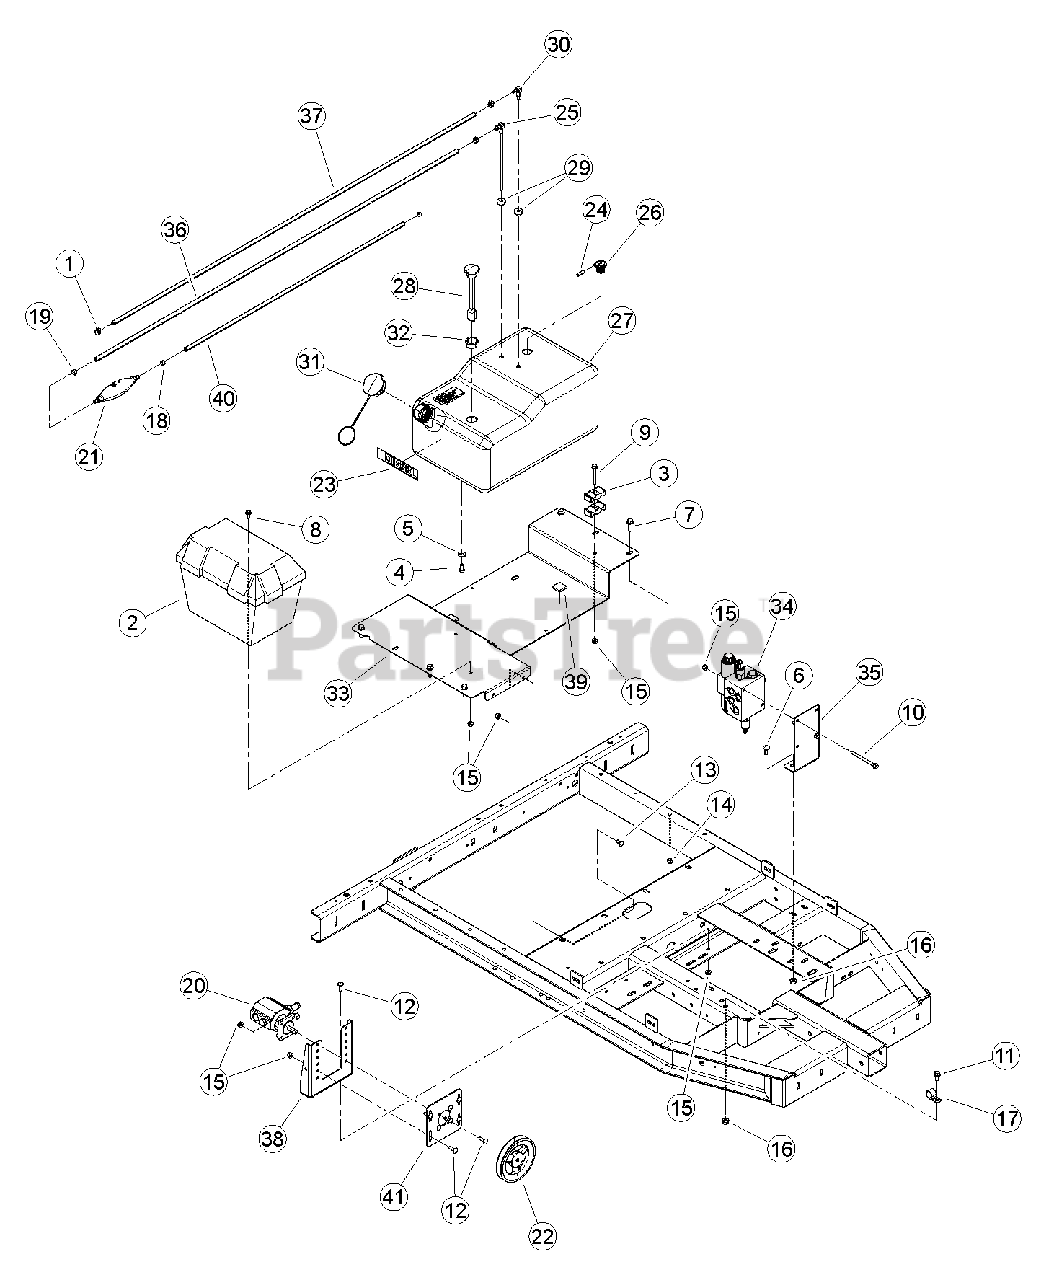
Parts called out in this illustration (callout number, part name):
1	CLAMP, HOSE 5/16 X 5/8 DIA MAX
2	BOX, PLASTIC BATTERY
3	CLAMP, PLASTIC HOSE
4	BOLT, 3/8 X 3/4 GR5 HEX CAPSCREW ZP
5	WASHER, 3/8" FLAT ZP
6	BOLT, 3/8 X 1" GR5 CRG NC ZP
7	BOLT, 3/8 X 1-1/4 FLANGE NC
8	BOLT, 5/16 X 3/4 FLANGE NC
9	BOLT, 5/16 X 2-1/2 FLANGE NC
10	BOLT, 5/16 X 4 SERRATED FLANGE NC
11	BOLT, 3/8 X 3/4 FLANGE NC
12	BOLT, 5/16 X 1" GR5 CRG ZP
13	BOLT, 5/16 X 3/4 GR5 CRG NC ZP
14	NUT, 3/8" NE NYLOCK ZP
15	NUT, 5/16-18 NYLOCK-FLANGE
16	NUT, 3/8-16 NYLOCK FLANGE
17	CLAMP, 1" COATED METAL
18	CLAMP, 15/32 SPRING
19	CLAMP, 9/16 SPRING
20	PUMP, 2 STAGE CW HI/LO 0.605 DISP.
21	PUMP, HAND PRIMER
22	PULLEY, 5.6 - 1/2" BORE FHP B
23	DECAL, DIESEL FUEL
24	CAP, EPDM BLACK .223 ID X 1.0 LG X .06 WALL
25	FITTING, TANK FUEL PICK-UP TUBE 5/16"
26	VALVE, ROLL OVER
27	TANK, ROTOMOLDED FUEL
28	GAUGE, FUEL LEVEL KELCH 100
29	GROMMET, TANK FITTING
30	FITTING, TANK VENT
31	CAP, FUEL TANK VENTED
32	GROMMET, KELCH 100 GAUGE
33	BASE, BATTERY BOX/FUEL TANK
34	ASSEMBLY, HYDRAULIC FEED FLOW VALVE W/ PS
35	PLATE, VALVE MOUNTING
36	HOSE, 63" FUEL LINE
37	HOSE, 63" RETURN LINE
38	BRACKET, MOUNT HYDRAULIC PUMP
39	PAD, FOAM FUEL TANK DAMPER
40	HOSE, 38" FUEL
41	PLATE, HYDRAULIC PUMP
